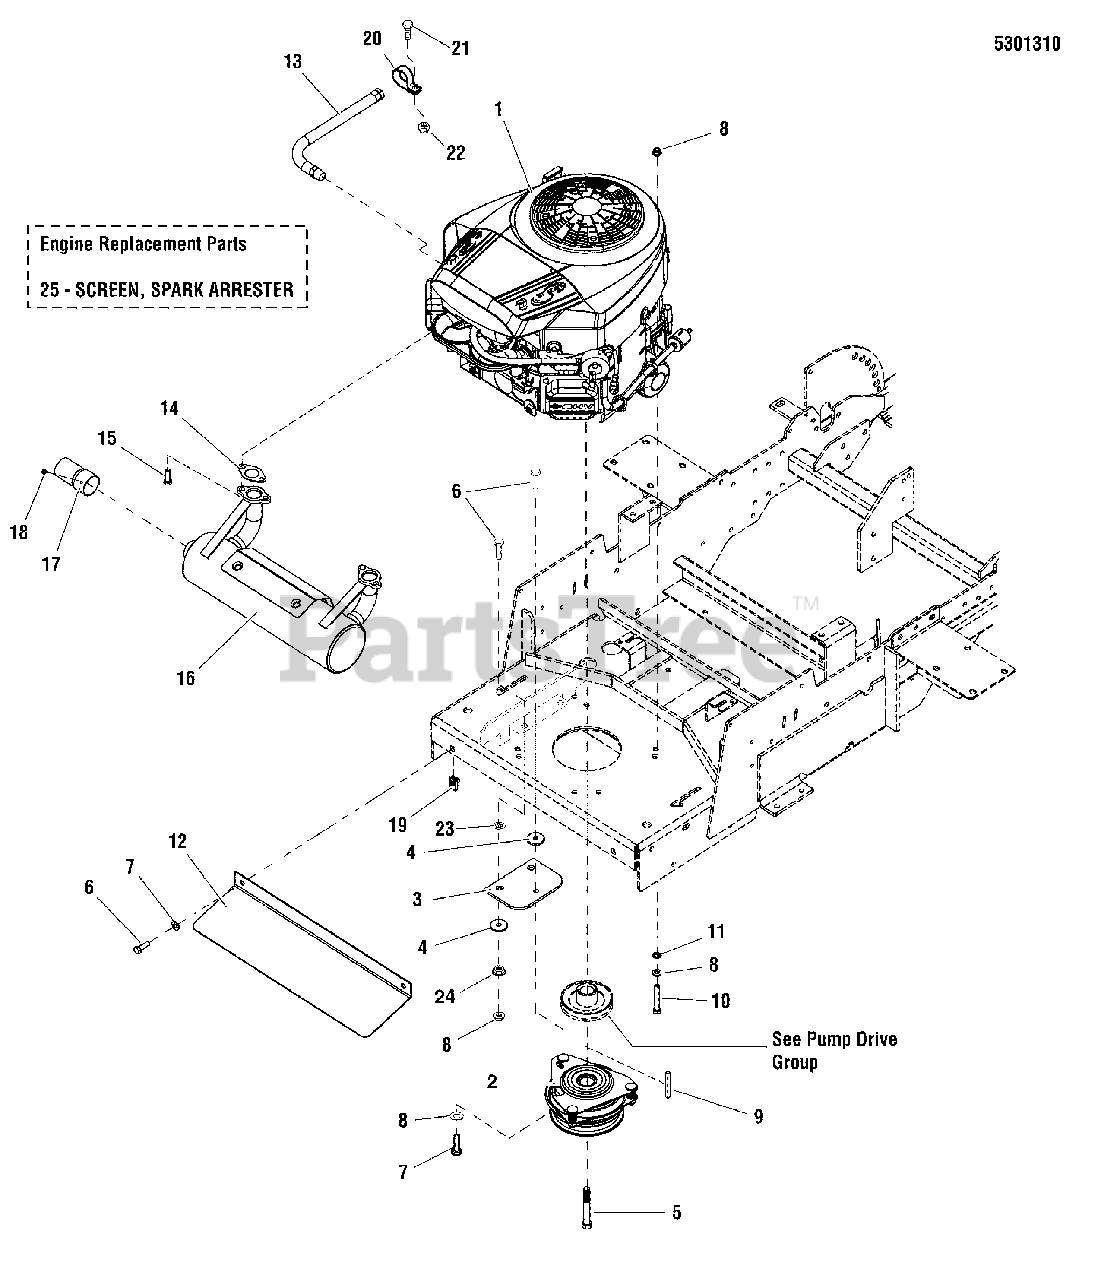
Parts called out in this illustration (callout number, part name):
1	* ENGINE, ELS BRIGGS
2	CLUTCH, WARNER ELECTRIC, I-5219-104
3	CLUTCH ANCHOR PAD
4	WASHER, .34 X 1.25 X 10 GA
5	BOLT, CRANKSHAFT, 7/16X2-3/4
6	BOLT, 5/16-18 X 1 GD5 YZ
7	WASHER, 5/16" SAE
8	NUT, 5/16-18 HEX NYLOCK FLANGE
9	KEY, 1/4 SQ. X 1.00
10	BOLT, 5/16-18 X 2 GD5 TFL
11	WASHER, 5/16" INT. TOOTH LOCK
12	PLATE, HEAT SHIELD - RED
13	HOSE, OIL DRAIN
14	* GASKET, EXHAUST
16	MUFFLER, B&S-ELS
17	EXTENSION, TAILPIPE, 3" - BLK
18	SCREW
19	BODY CLIP, 5/16-18 X 1/2 DEEP
20	CLAMP, VINYL INSULATED
21	BOLT, 1/4-20 X 3/4 GD5 YZ
22	NUT, 1/4-20 HEX NYLOCK FLANGE (5025391)
23	5/16" PUSH-ON NUT RETAINER, STL, CZ
24	NUT, 5/16-18 HEX SERRATED FLANGE (LARGE)
25	SCREEN, SPARK ARRESTER
